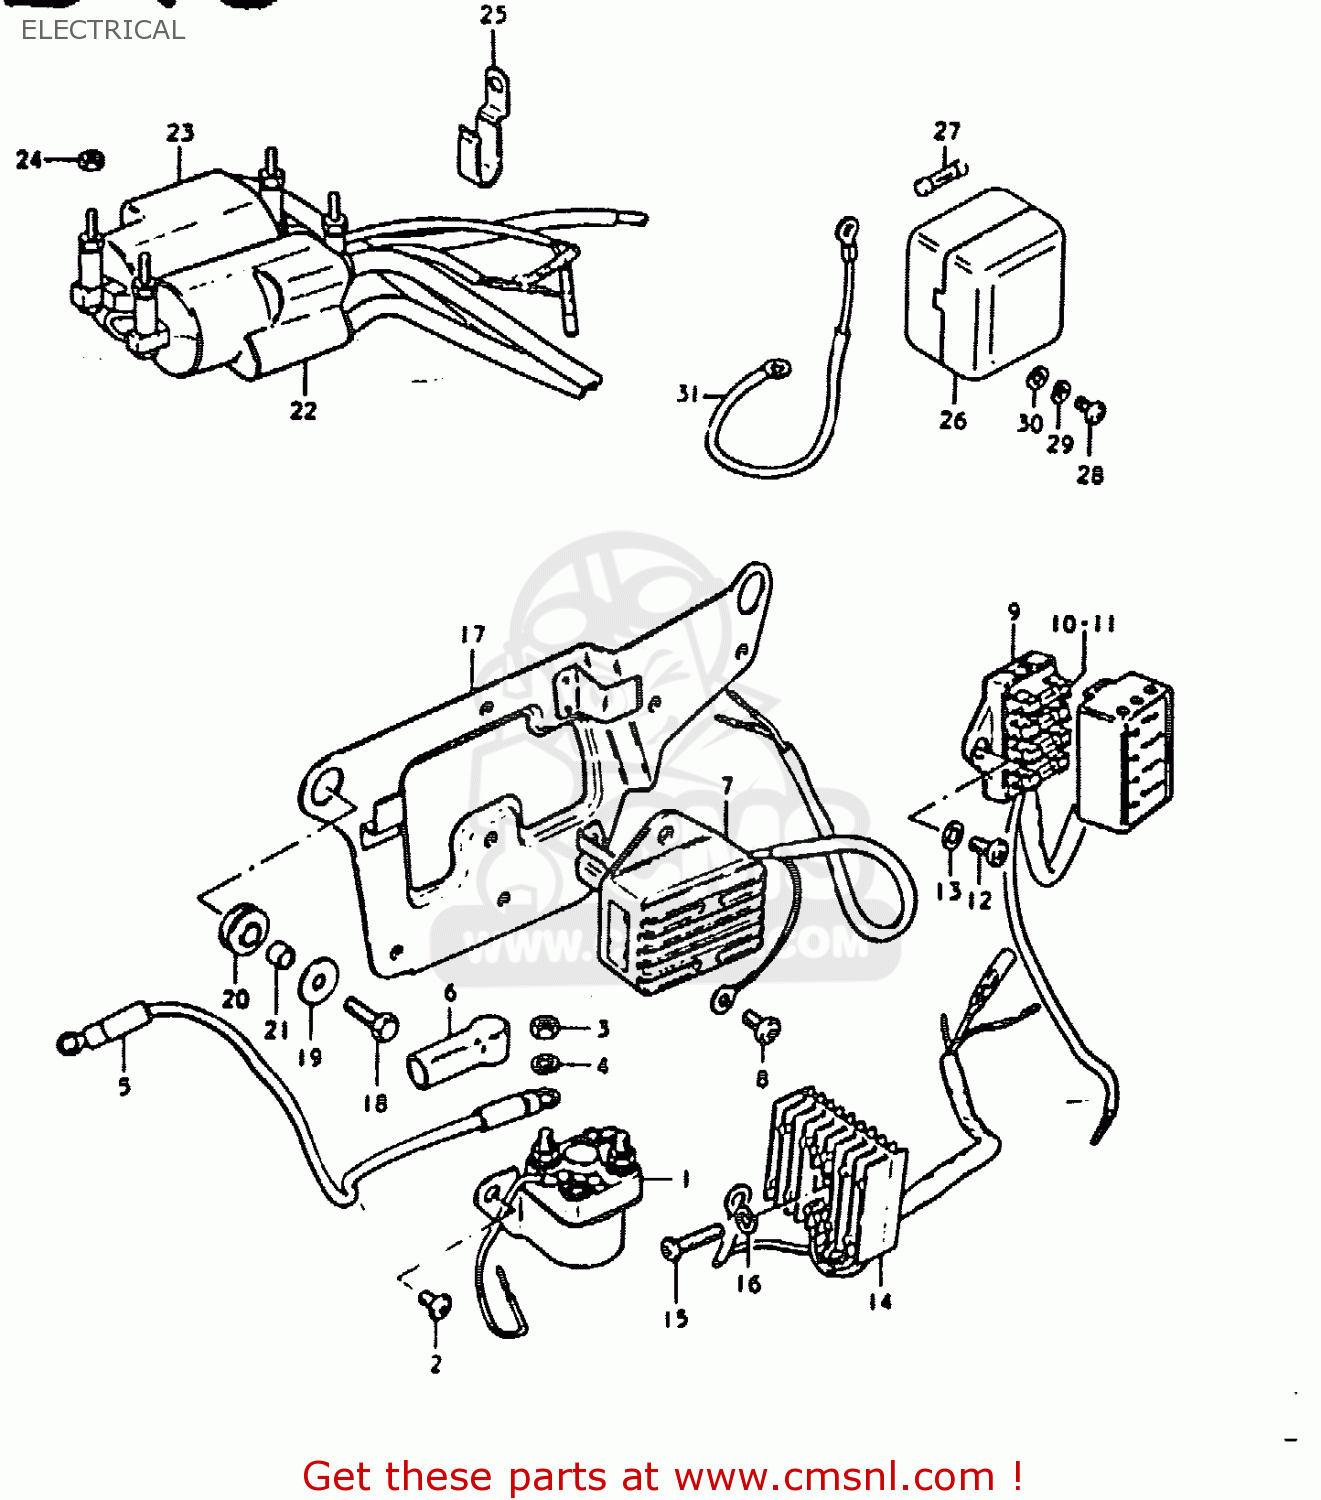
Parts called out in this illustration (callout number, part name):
1	RELAY ASSY,STARTING MOTOR
2	SCREW
3	NUT 6MM
4	LOCK WASHER
5	WIRE,STARTER MOTOR LEAD
6	CAP,STARTER RELAY
7	REGULATOR ASSY,VOLTAGE
8	SCREW
9	BOX ASSEMBLY,FUSE
10	FUSE(10A)
11	FUSE(15A)
12	SCREW 6X12
13	WASHER 6MM
14	RECTIFIER ASSEMBLY
15	SCREW
16	LOCK WASHER
17	HOLDER COMP,ELECTRONIC PARTS
18	BOLT, UPPER
19	WASHER(6,5X22X1.6)
20	CUSHION
21	SPACER(6.2X8.3X5.7)
22	COIL ASSEMBLY,IGNITION
23	COIL ASSEMBLY,IGNITION
24	NUT
25	CLAMP
